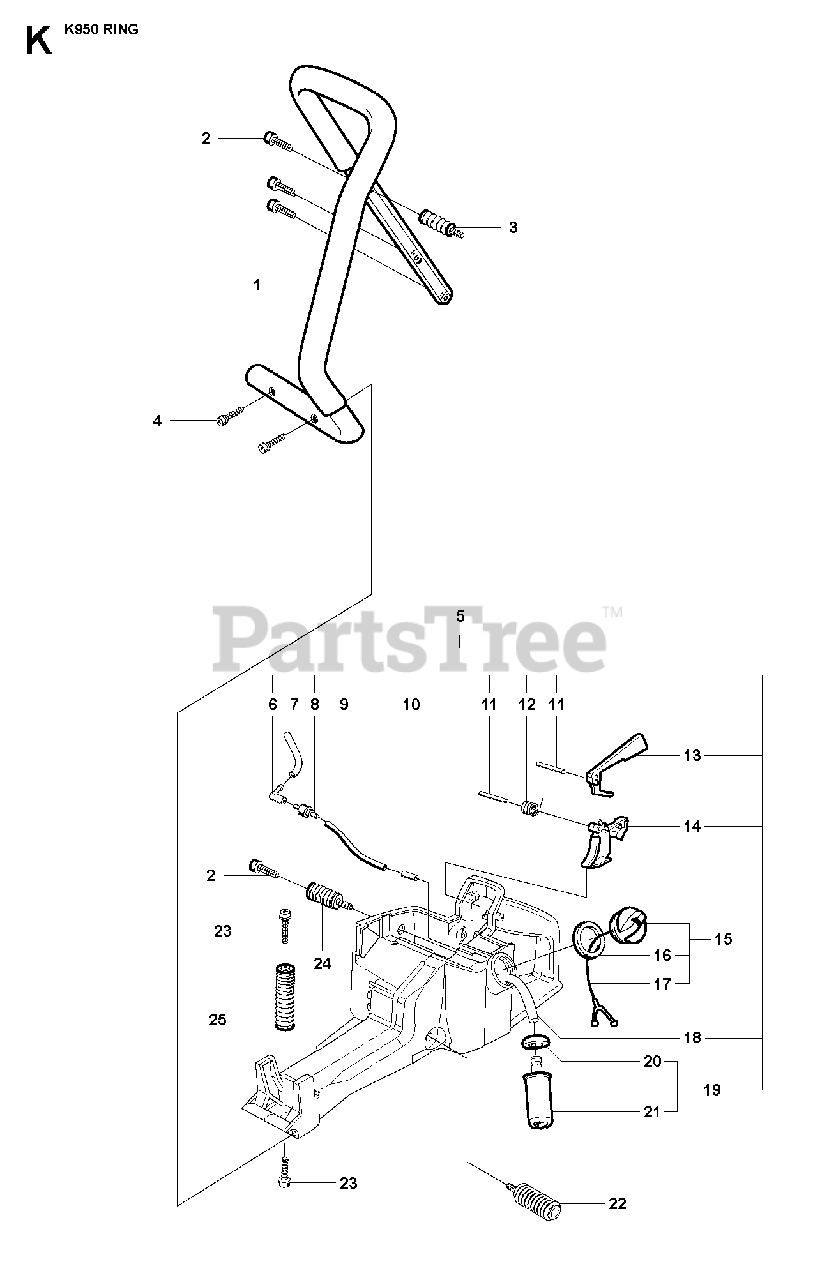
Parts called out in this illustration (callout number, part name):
3	ANTIVIBRATION ELEMENT
5	FUEL TANKIncl. 6 - 15, 18, 19
6	CONNECTION BEND
7	FUEL HOSE
11	PARALLEL PIN
12	SPRING THROTTLE TRIG
13	THROTTLE LOCKOUT
15	TANK CAP ASSYIncl. 16, 17
18	FUEL HOSE
19	FUEL FILTERIncl. 20, 21
23	SCREW IHSCFM
24	ANTIVIBRATION ELEMENT
25	ANTIVIBRATION ELEMENT
